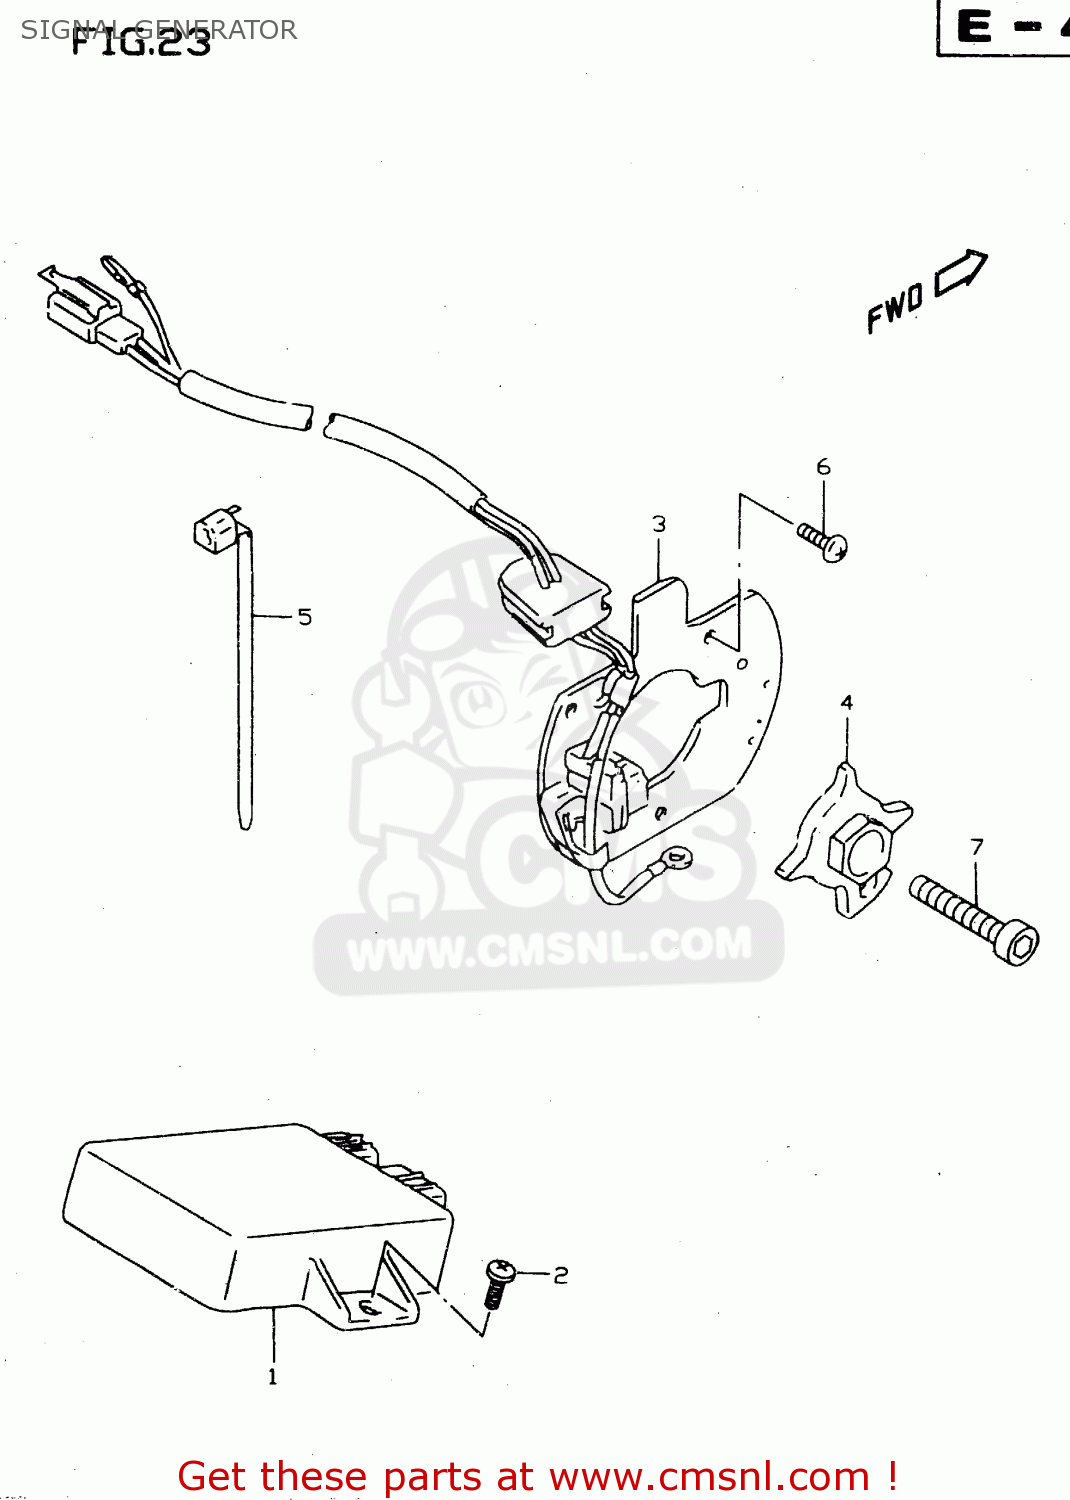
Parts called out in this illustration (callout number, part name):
1	IGNITOR ASSY
2	SCREW 6X12
3	GENERATOR ASSY,SIGNAL
4	ROTOR,SIGNAL GENERATOR
5	CLAMP(L:125)
6	SCREW
7	BOLT
